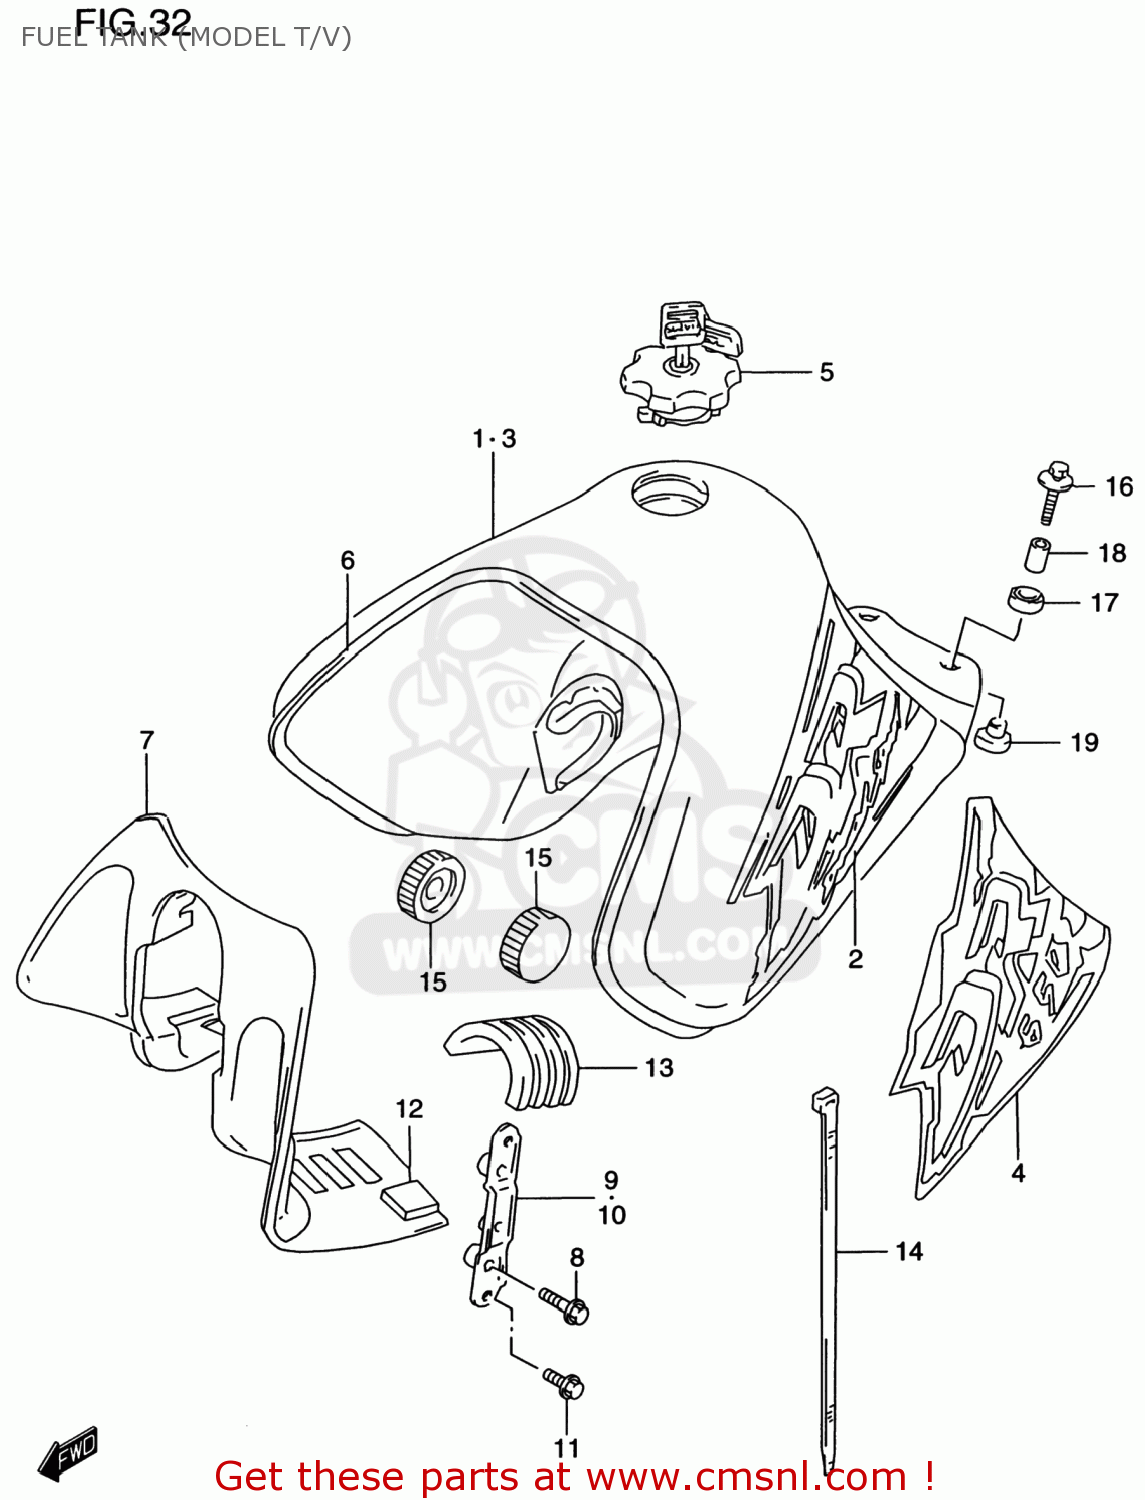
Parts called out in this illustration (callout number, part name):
1	TANK ASSEMBLY,FUEL
2	TAPE SET,FUEL TANK
3	TANK ASSEMBLY,FUEL
4	TAPE SET,FUEL TANK
5	CAP SET,FUEL TANK
6	MOLDING,FUEL TANK
7	COVER,FUEL TANK FR
8	BOLT 6X14
9	BRACKET,FUEL TANK COVER,R
10	BRACKET,FUEL TANK COVER,L
11	BOLT
12	CUSHION,HEADLAMP COVER
13	CUSHION,FUEL TANK UPR
14	CLAMP(L:250)
15	CUSHION,FUEL TANK FR
16	BOLT(6X30)
17	CUSHION
18	SPACER(6.5X9X18)
19	CUSHION
